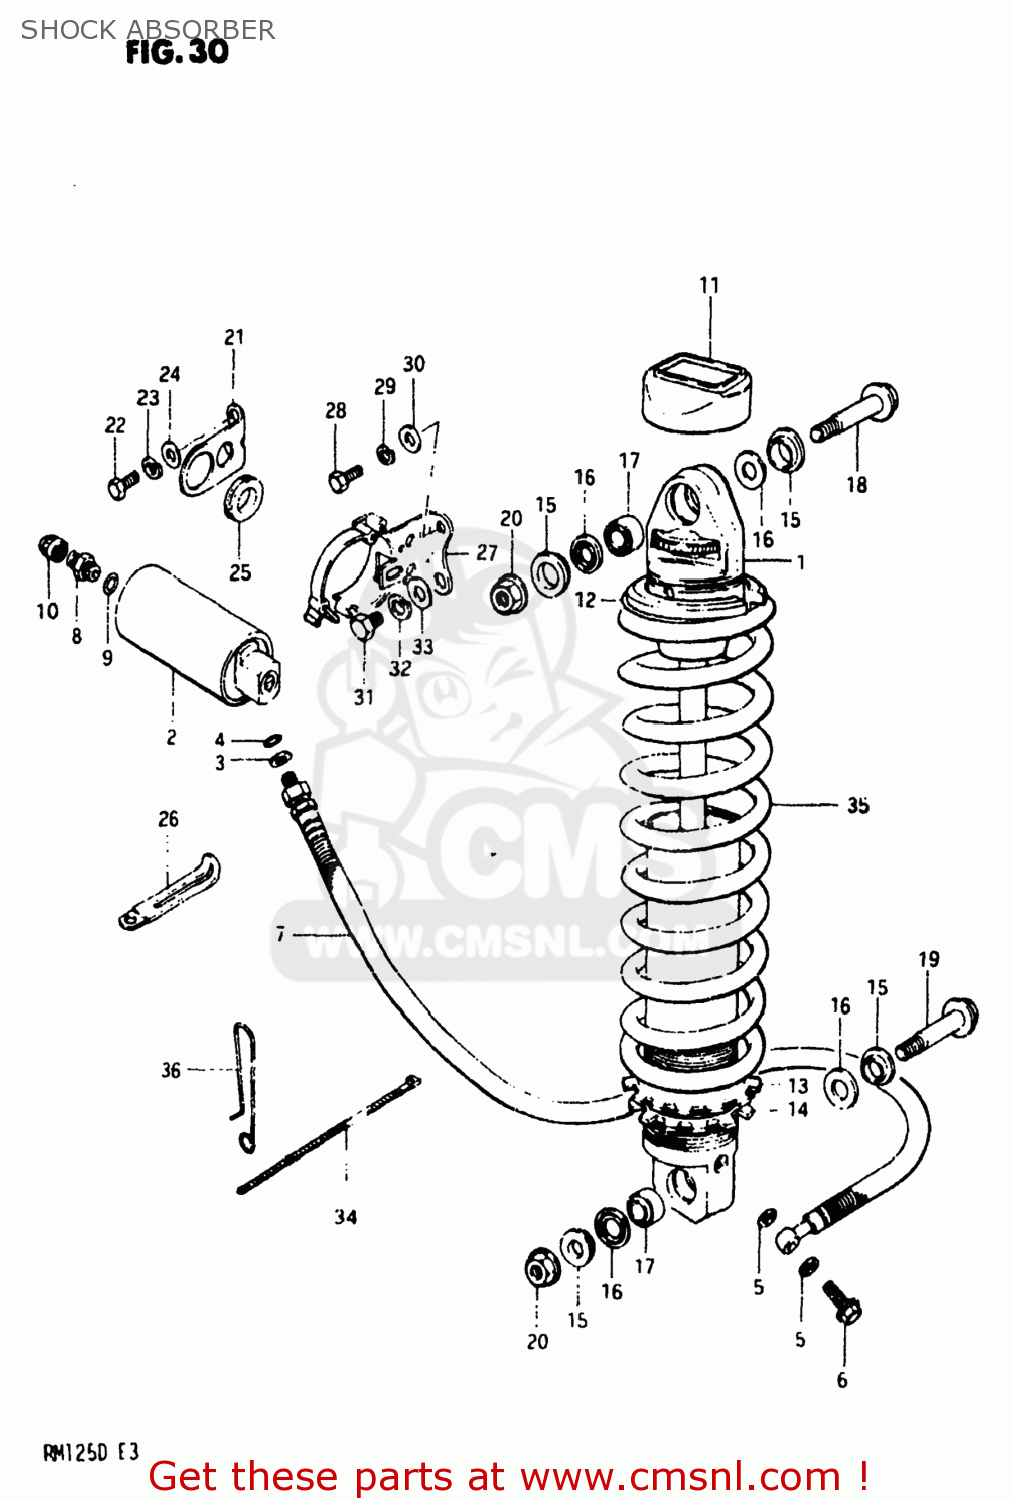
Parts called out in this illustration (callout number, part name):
1	ABSORBER ASSEMBLY,REAR SHOCK
2	RESERVE TANK,REAR SHOCK
3	WASHER,REAR SHOCK HOSE
4	O-RING,RESERVE TANK
5	GASKET (NAS)
6	BOLT,REAR SHOCK ABSORBER
7	HOSE,REAR SHOCK ABSORBER
8	VALVE,FRONT FORK AIR
9	O-RING
10	CAP
11	CLIP
12	SPRING GUIDE
13	GUIDE,SPRING
14	GUIDE,REAR SHOCK ABSORBER SPRING
15	COLLAR
16	DUST SEAL,LWR
17	BEARING
18	BOLT
19	BOLT(10X54)
20	NUT
21	BRACKET,RESERVOIR TANK
22	BOLT
23	LOCK WASHER
24	WASHER
25	CUSHION,RESERVOIR TANK
26	CLAMP
27	BRACKET,RESERVOIR TANK
28	BOLT
29	LOCK WASHER
30	WASHER
31	BOLT
32	LOCK WASHER
33	WASHER
34	CLAMP
35	SPRING
36	GUIDE RES HOSE CLAMP
